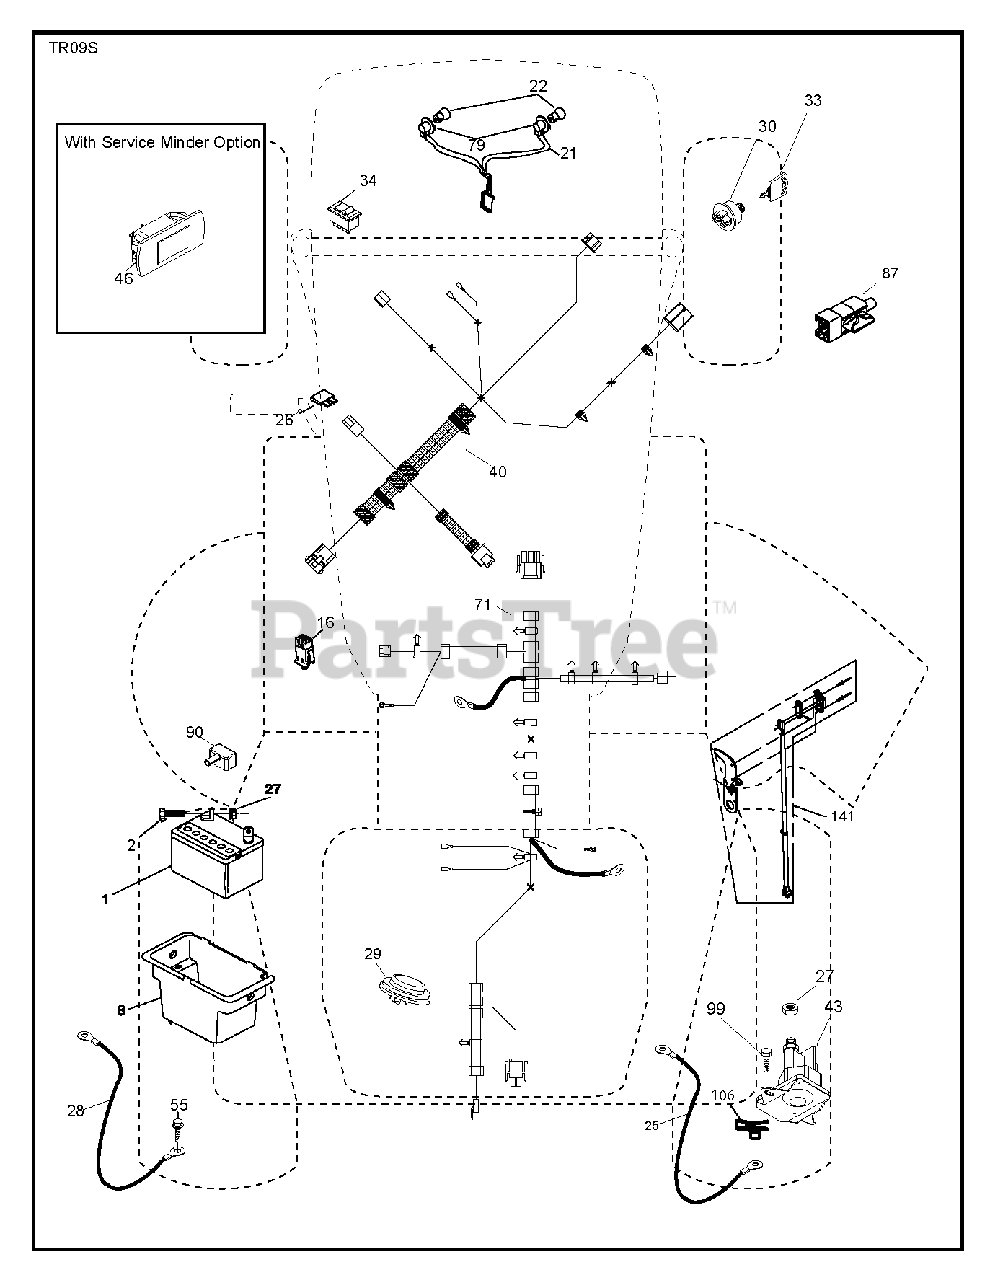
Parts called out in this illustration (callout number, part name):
1	REPL BY 532 12 38-99
2	BOLT.HEX.1/4.X.3/4.DICHROMATE
8	BOX.BATTERY.MNT.REAR.L
16	SWITCH INTERLOOK PUSH-IN
21	HARNESS.LIGHT W/4152J BULBS
25	CABLE.BATT.RED.8GA.17
26	FUSE 20AMP
27	NUT
28	CABLE.GROUND.REAR.BATTERY.8G
29	SWITCH.SEAT.DELTA.OPC.
30	SWITCH.IGN.DELTA.W.LGH.ROS
33	KEY.CHAIN.BLISTER.PACK.GEN.USA
40	HARNESS.TEX.DASH.MAN.REAR BATT
43	SOLENOID.W/BRASS.PLUNGER
46	RP GUAGE.SRVCMNDR.HRMTR.
55	SCREW 5/16"
71	HARNESS.TEX.CHSSIS.REAR.BATT
79	BULB HOLDER ASM.
87	SWITCH.INTRLCK.CLUTCH.
90	COVER.TERMINAL.BATTERY
99	SCREW HEXWSHR 1/4-20X3/4
106	1/4-20 U NUT
141	KIT T2.ROS 71677
